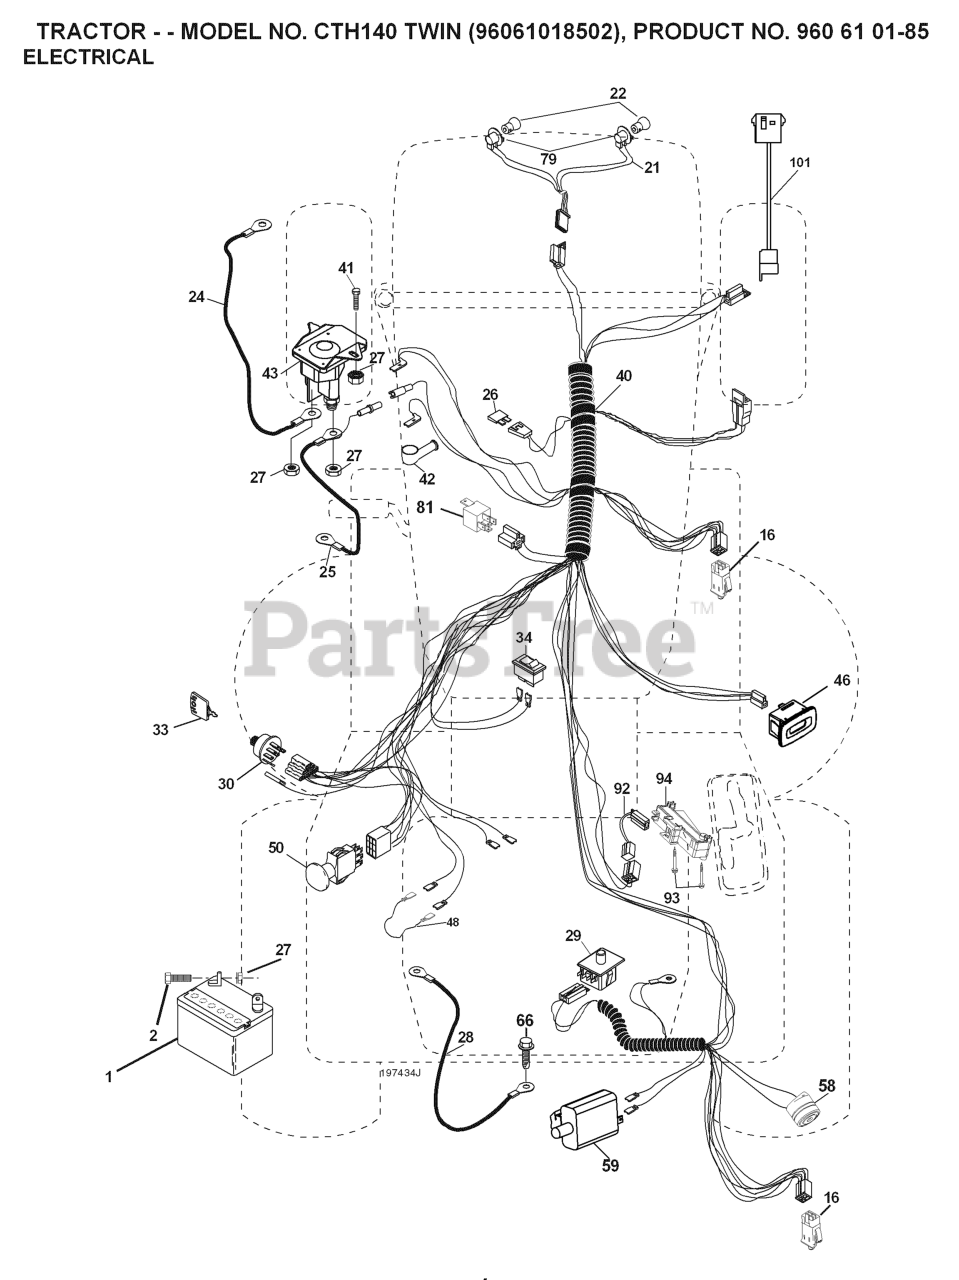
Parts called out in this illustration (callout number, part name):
1	BATTERY 12V .35 AMP
2	BOLT.HEX.1/4.X.3/4.DICHROMATE
16	SWITCH INTERLOOK PUSH-IN
21	HARNESS.LIGHT W/4152J BULBS
24	BATTERY CABLE GT
25	CABLE BATTERY
26	FUSE 20AMP
27	NUT
28	CABLE GROUND
29	SWITCH.SEAT.DP W/RAMPS
30	SWITCH.IGN.DELTA.W.LGH.ROS
33	KEY MLD GEN DELTA
40	RP HARNESS.IGN.ELECT.REG.CRD
41	BOLT
42	TERMINAL COVER
43	SOLENOID.W/BRASS.PLUNGER
46	RP.GUAGE.SRVCMNDR.HRMTR.
48	ADAPTER.AMMETER
50	RP.PTO.SWITCH.8 TERMINAL.BLACK
58	BUZZER
59	.WITCH.FULL BAGGER.INDICATOR
79	BULB HOLDER ASM.
81	RELAY.ASSY.T
92	HARNESS.PIGTAIL.CONSLE
93	SCREW.PLASTITE
94	MODULE.REVERSE.ROS
101	PIGTAIL.MATNLK.NEW.HAR
